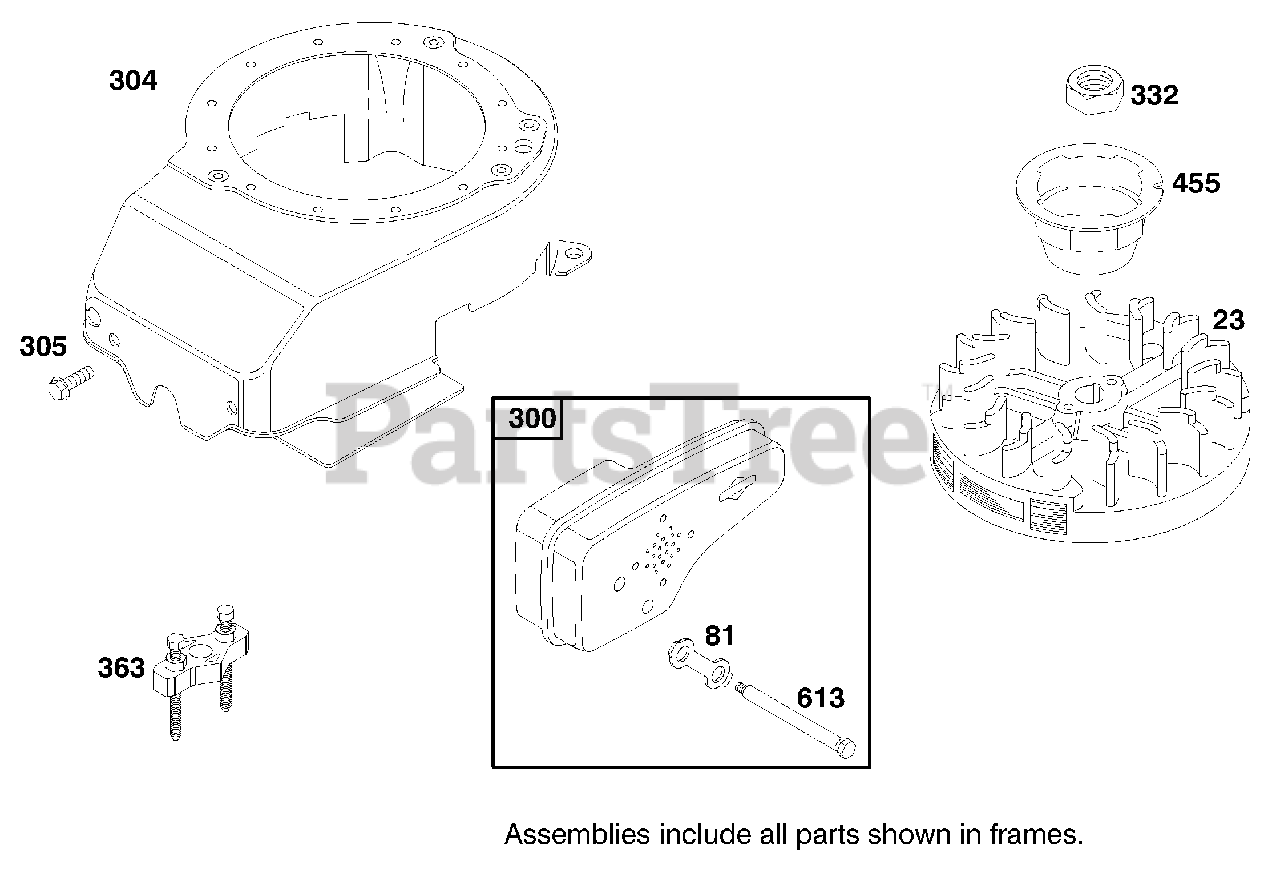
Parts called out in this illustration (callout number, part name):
23	Flywheel
81	Lock-Muffler Screw
300	Muffler-Exhaust
304	Housing-Blower
305	Screw-Hex
332	Nut-Flywheel
363	Flywheel Puller
455	Cup-Flywheel
613	Screw-Shoulder
